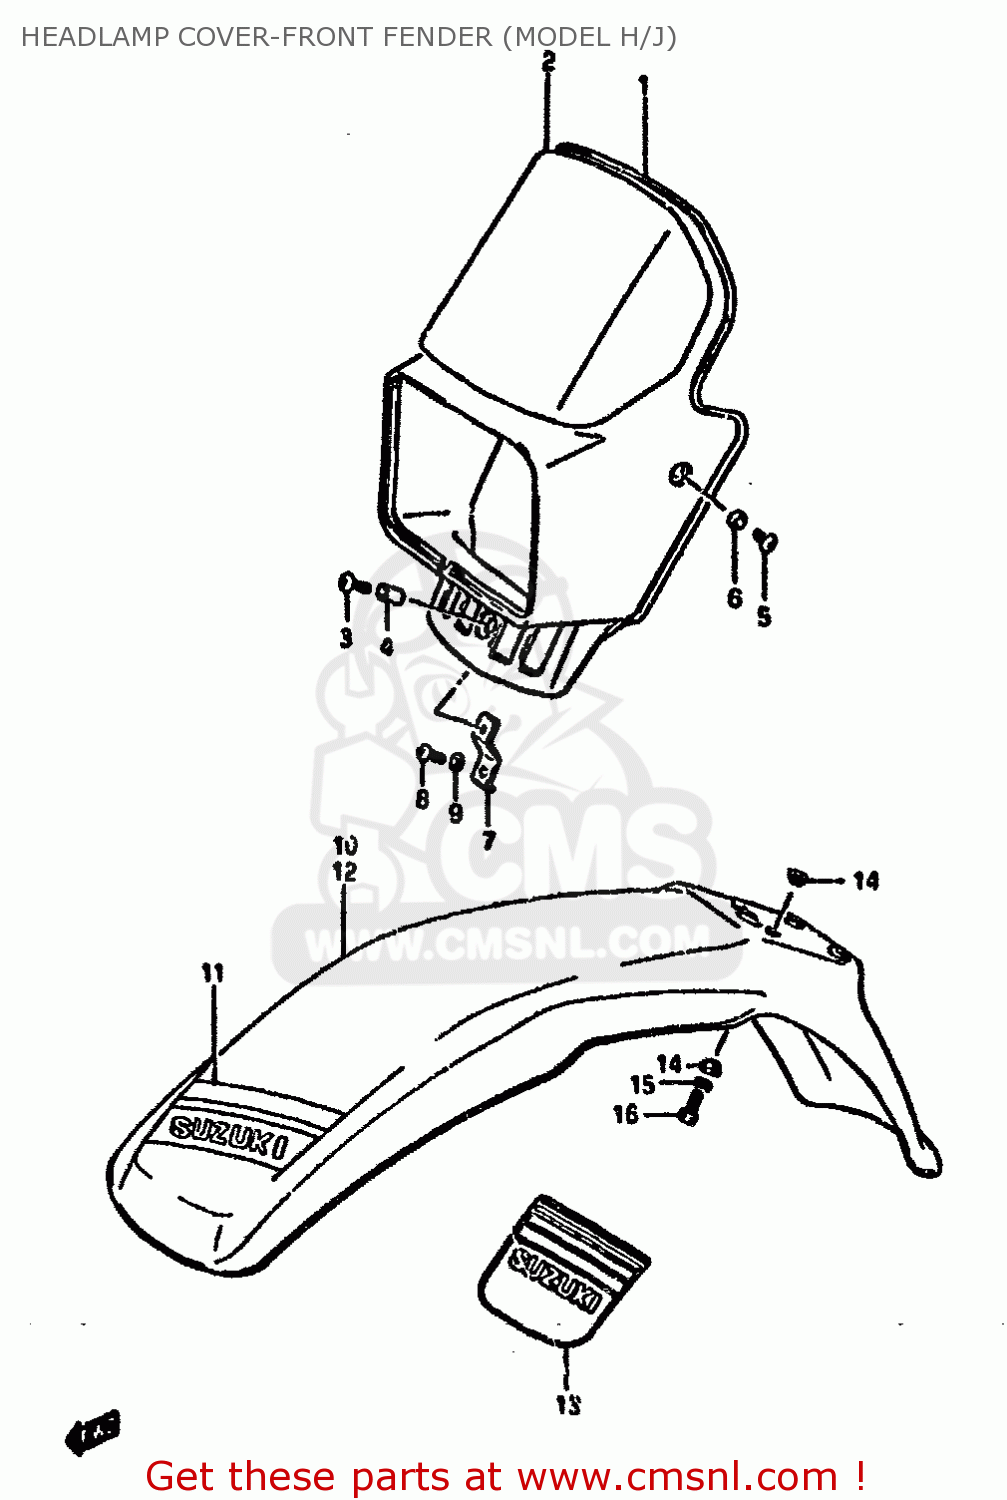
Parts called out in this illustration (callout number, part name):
1	COVER,HEADLAMP
2	TAPE SET
3	SCREW, CENTER
4	SPACER (6.1X8X12)
5	SCREW 6X12
6	SPACER (6.1X8X3.5)
7	BRACE,HEADLAMP HOUSING LWR
8	SCREW 6X12
9	WASHER,LOCK
10	FENDER,FRONT (BLUE)
11	TAPE SET
12	FENDER,FR
13	TAPE,FR FENDER
14	WASHER
15	WASHER,LOCK
16	BOLT
